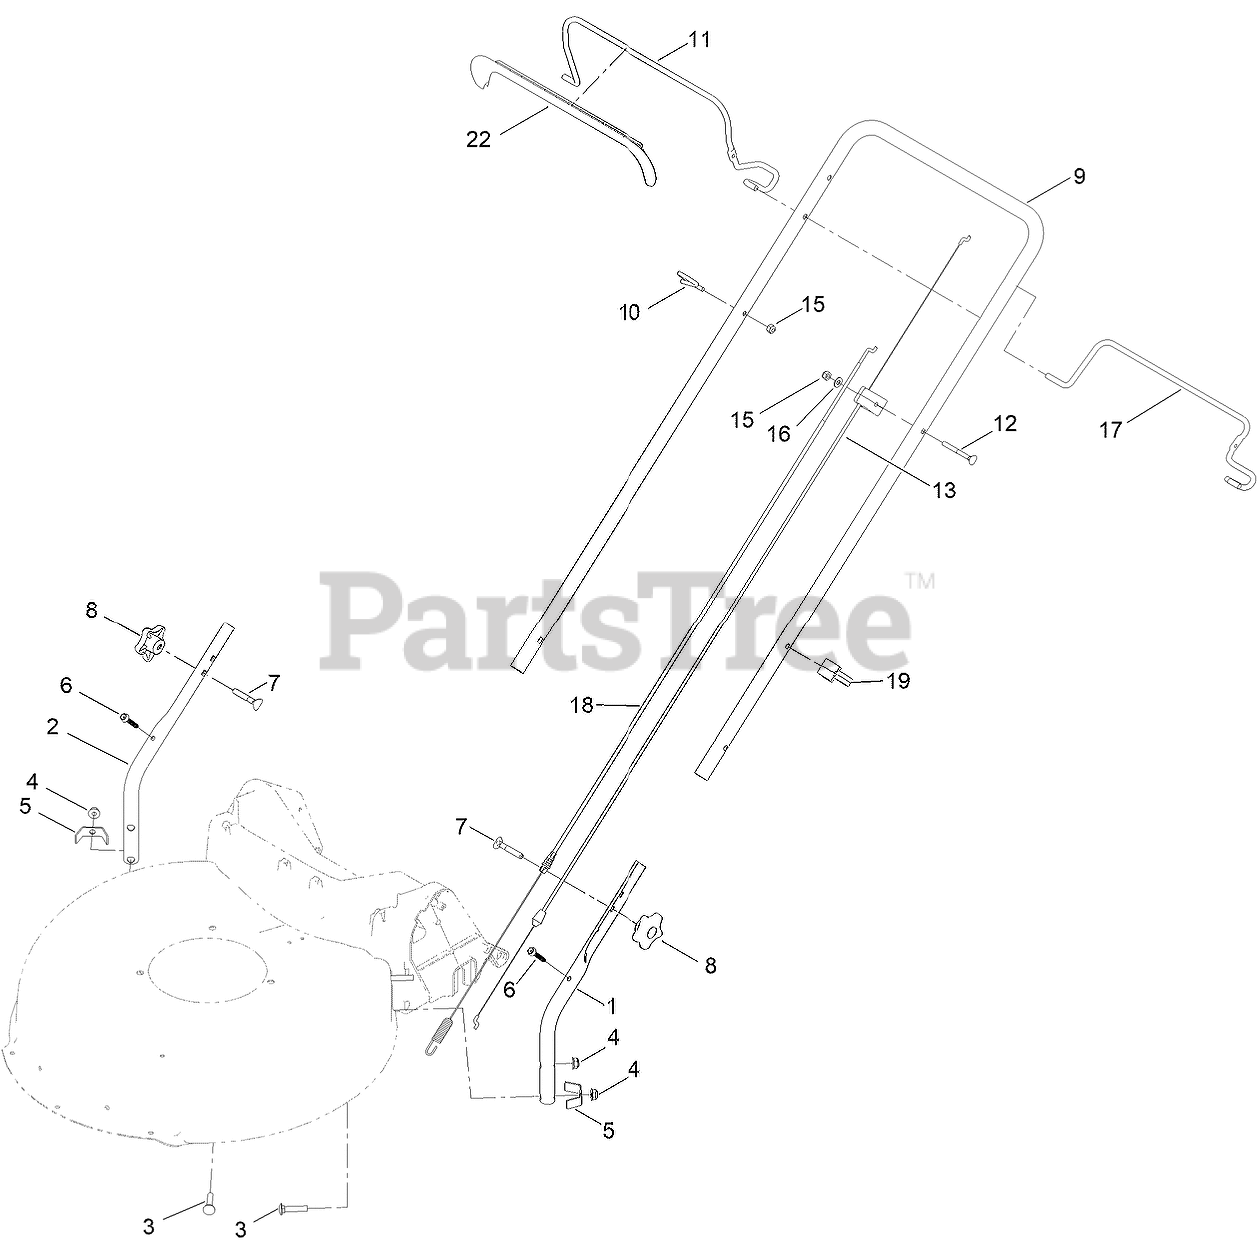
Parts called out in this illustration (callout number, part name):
1	HANDLE-LOWER, LH
2	HANDLE-LOWER, RH
3	SCREW-CARR
4	NUT-HF
5	BRACKET-CHUTE
6	SCREW-FLANGE, SERRATED
7	SCREW-HANDLE
8	KNOB-HANDLE
9	HANDLE-UPPER
10	GUIDE-ROPE
11	BAIL-BRAKE
12	SCREW-HANDLE
13	CABLE-BRAKE
15	NUT-HEX
16	WASHER-FLAT
17	BAIL-TRACTION
18	CABLE-TRACTION
19	GUIDE-CABLE
22	COVER-BAIL
